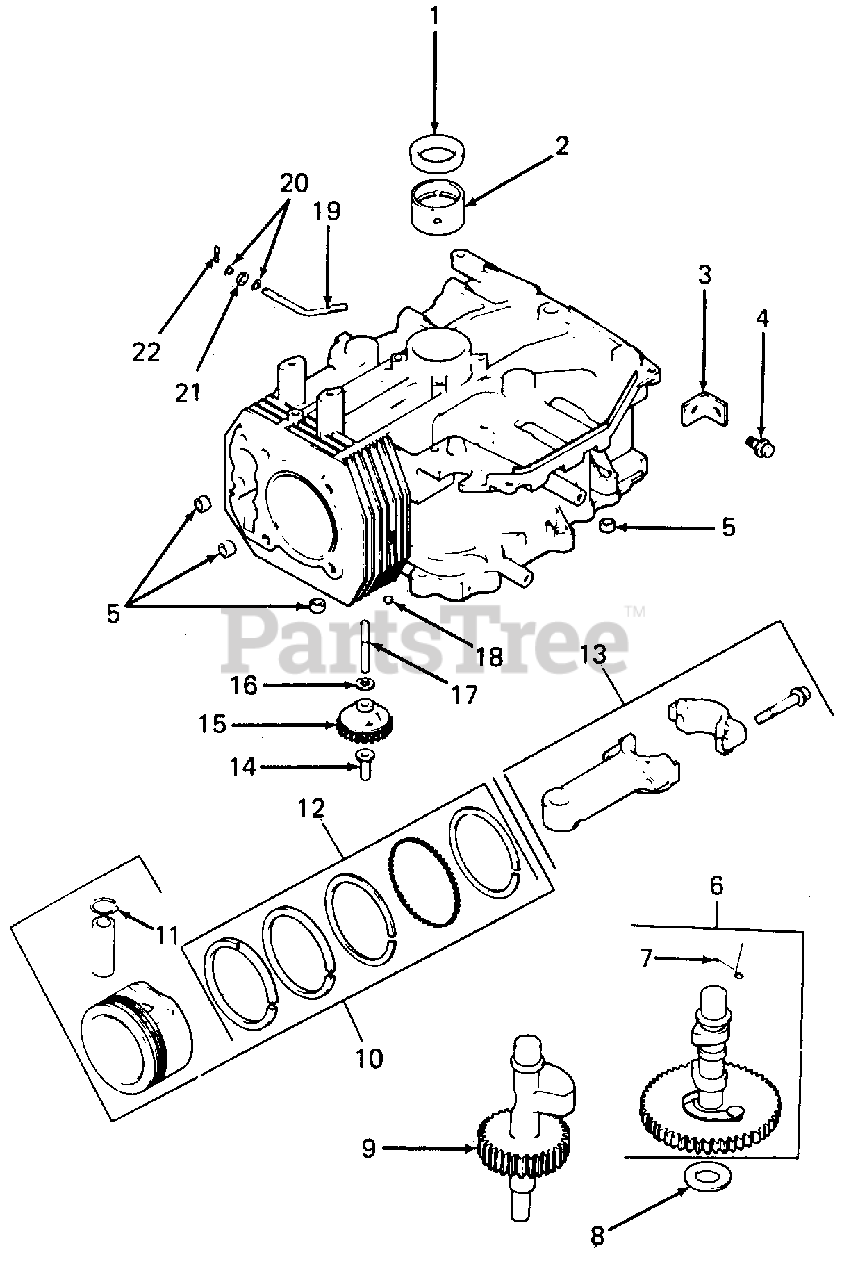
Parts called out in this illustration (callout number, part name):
1	Seal, Crankshaft
2	Bearing, Crankshaft, Std
3	Strap, Lifting
4	Screw, Lifting Strap, M8 X 1.25 X 25.5
5	Dowel, Locating
6	Camshaft Assy
7	Spring, Actuating
8	Shim, Camshaft
9	Shaft, Balance
10	Piston w/Ring Set, Std
11	Retainer, Piston Pin
12	Ring Set, Std
13	Connecting Rod, Std
14	Pin, Governor Regulating
15	Gear, Governor
16	Washer, Governor Gear Thrust
17	Shaft, Governor Gear
18	Plug, Cup
19	Shaft, Governor Cross
20	Washer, Governor Shaft
21	Seal, Governor Cross Shaft
22	Pin, Governor Hitch
